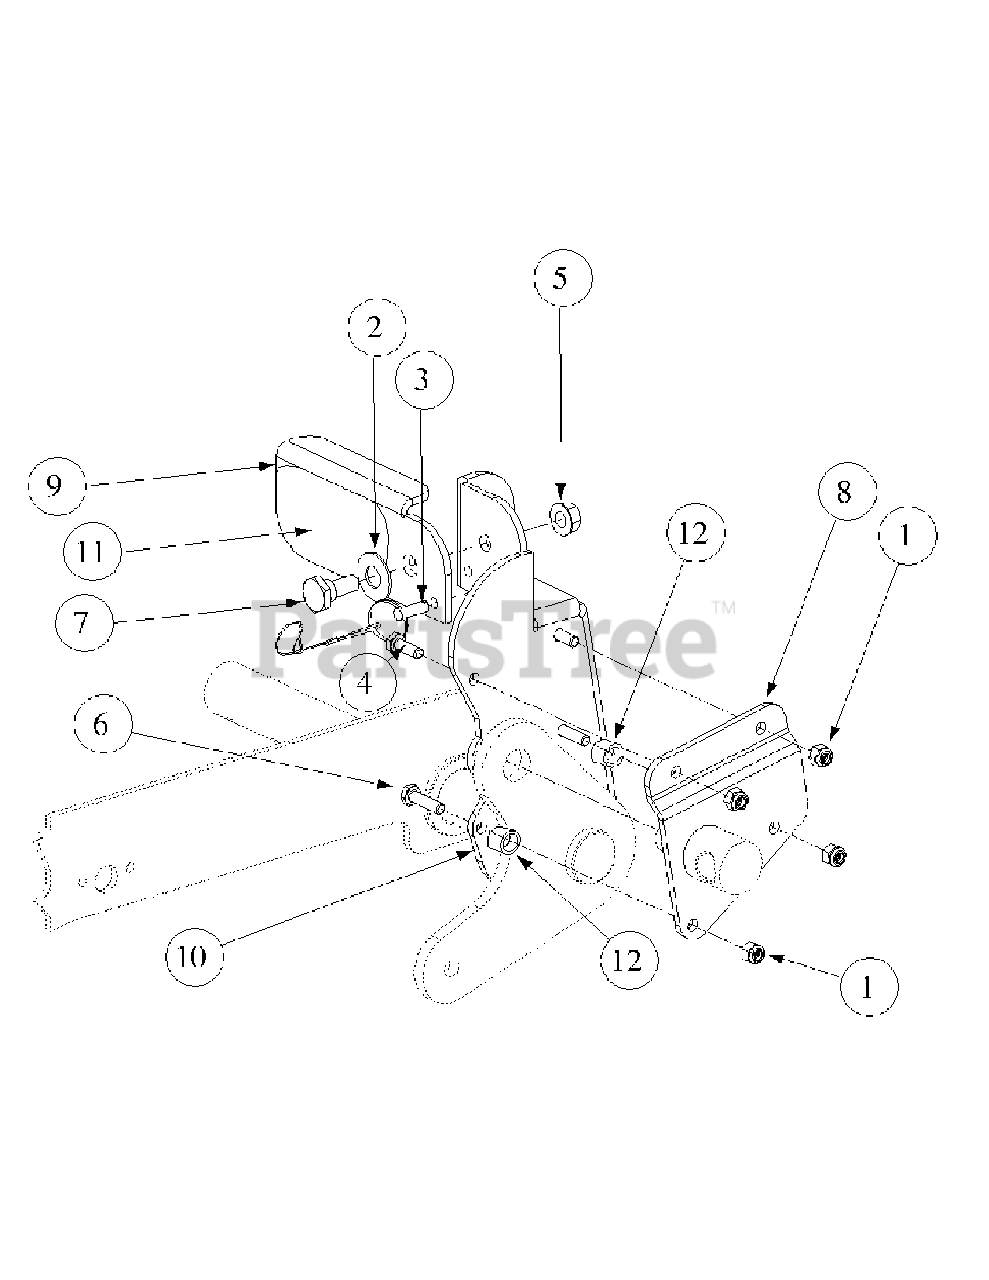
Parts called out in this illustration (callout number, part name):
1	Lock Nut, Nylon Insert, 1/4-20
2	Washer, 1/2 x 1 Shim
3	Detent Pin w/12" Lanyard
4	Hex Cap Screw, 1/4-20, .75
5	Hex Nut, Flange Lock 3/8-16
6	Hex Cap Screw, 1/4-20, 1.00
7	Shoulder Screw, .50 x .27 Lg., 3/8-16
8	Foot Lift Backup Pedal
9	Deck Foot Pedal Lift
10	Deck Foot Pedal Lift
11	Deck Foot Lift Pad
12	Turnbuckle Sleeve
